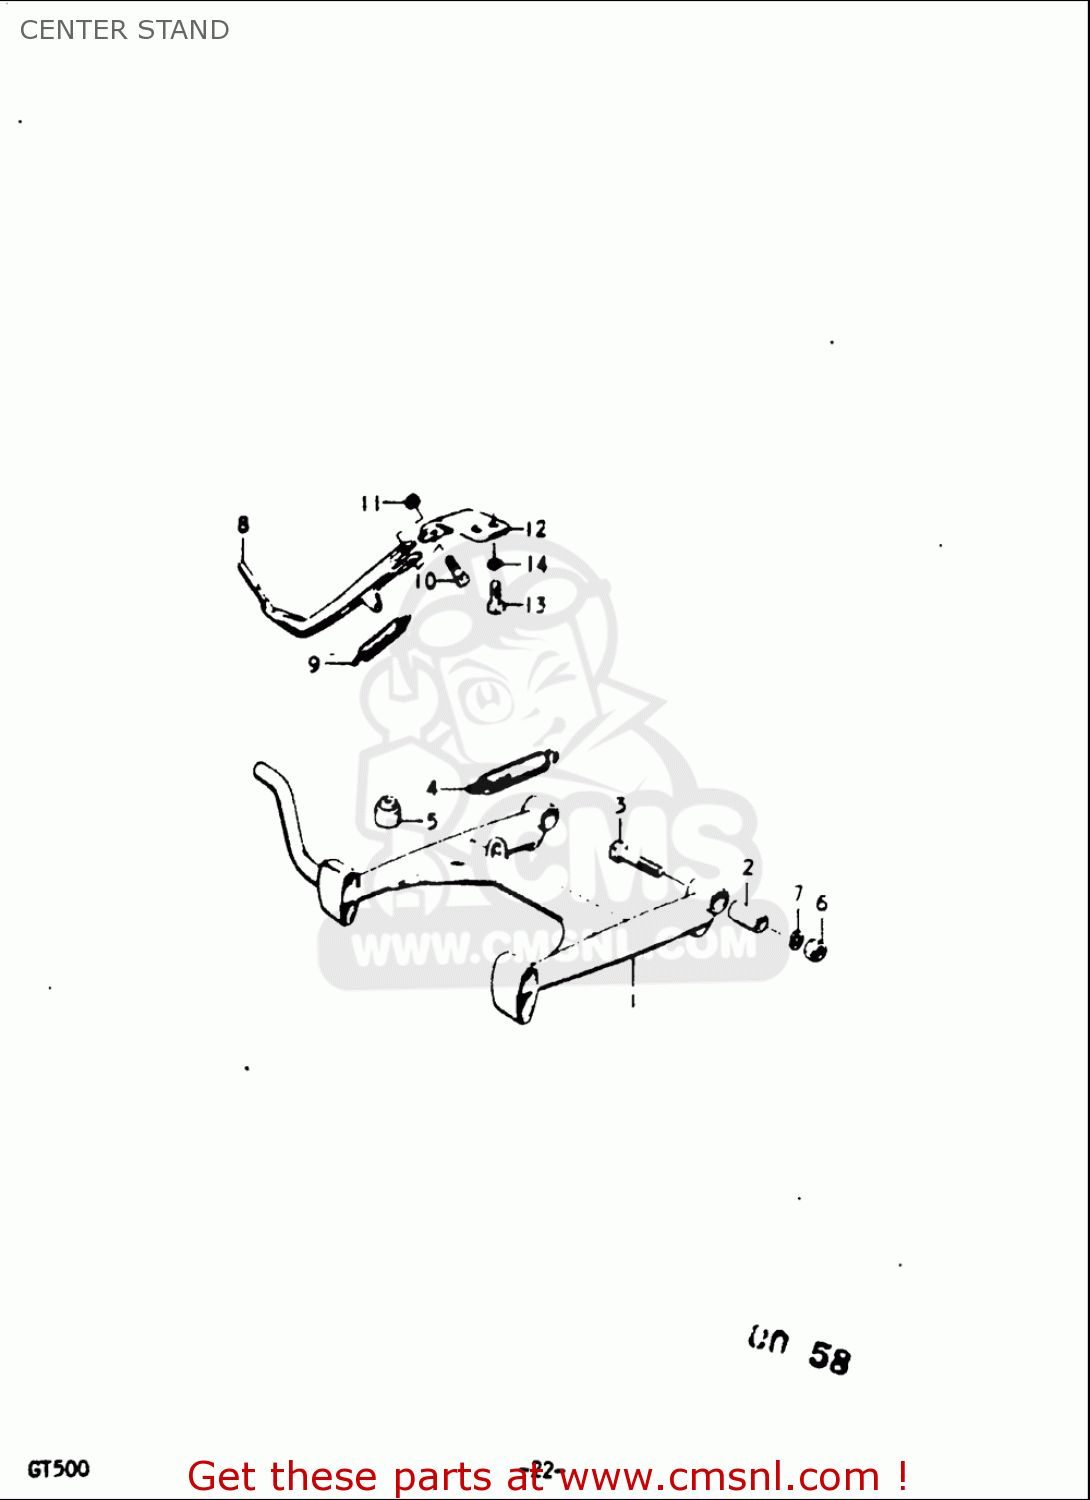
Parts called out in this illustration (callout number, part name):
2	SPACER(10.5X16X30)
3	BOLT(10X48)
4	SPRING
5	CUSHION
6	NUT
7	WASHER,LOCK
9	SPRING
10	BOLT(10X27)
11	NUT
13	BOLT
14	WASHER,LOCK
